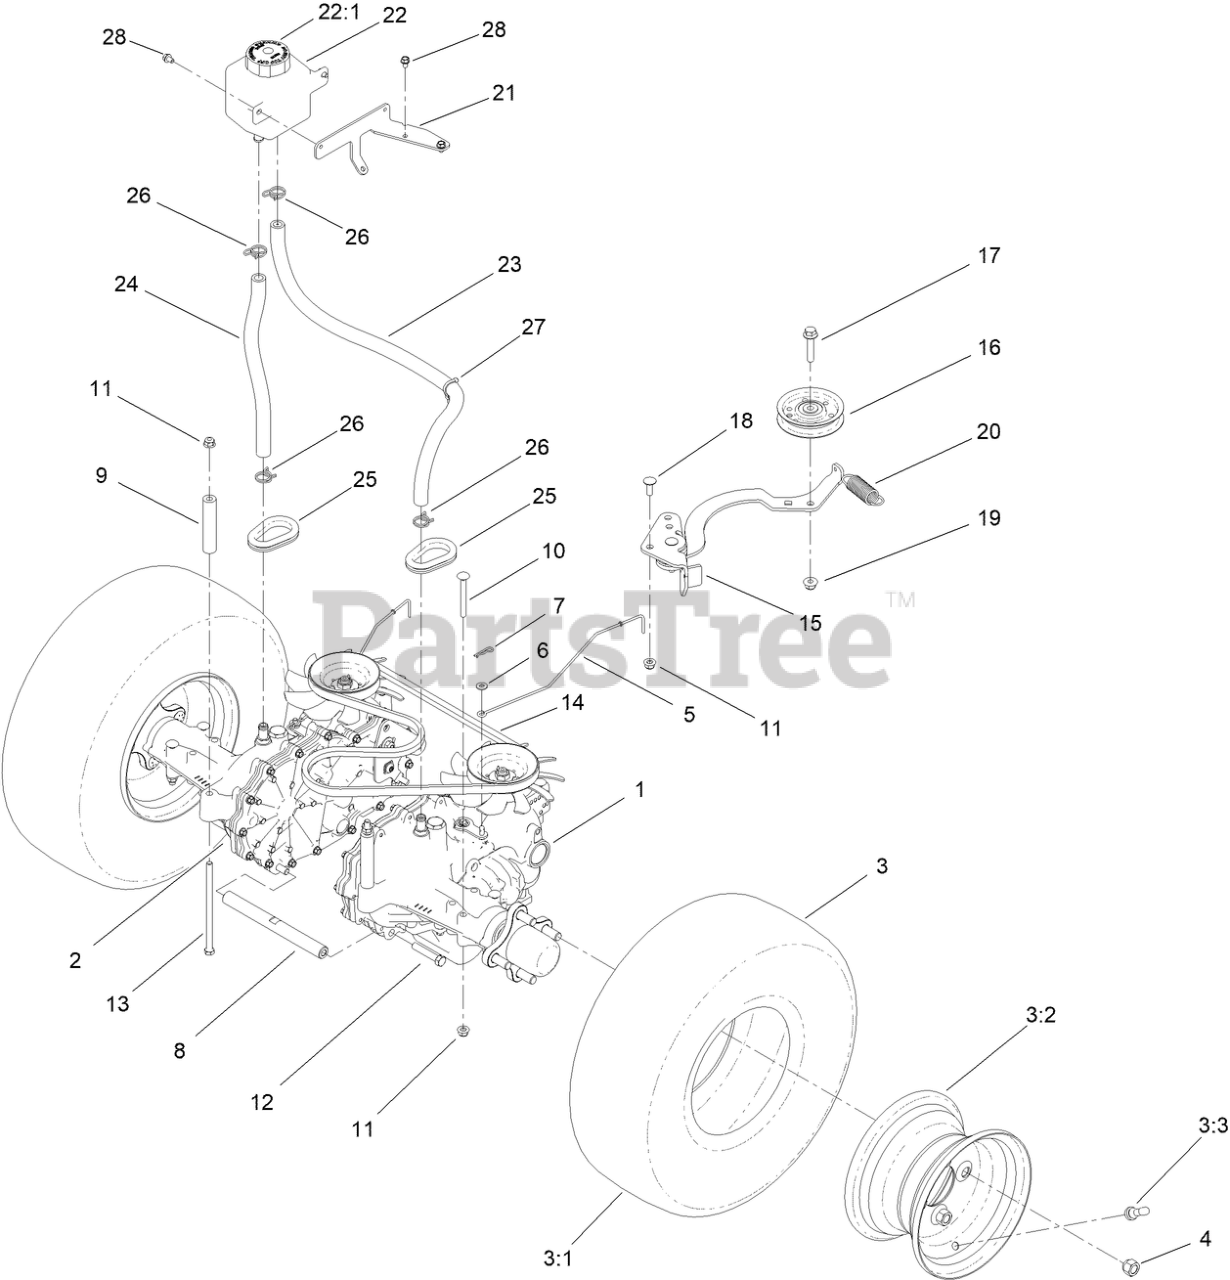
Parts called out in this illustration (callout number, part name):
1	TRANSMISSION, ZT-3100 LH
2	TRANSMISSION, ZT-3100 RH
3	WHEEL AND TIRE ASM
3:1	TIRE-4 PLY
3:2	RIM-8"
4	NUT-LUG
5	ROD-BYPASS
6	WASHER-FLAT
7	PIN-COTTER
8	SHAFT-CROSS, HYDRO
9	SPACER - TRANSMISSION
10	SCREW-CARR
11	NUT-HF, NI
12	SCREW-HH W/LOCTITE
13	SCREW-HH
14	BELT-V
15	IDLER ARM PIVOT ASM
16	PULLEY-IDLER, FLAT
17	SCREW-HHF
18	BOLT-CARR
19	NUT-HF, NI
20	SPRING-EXTENSION
21	BRACKET - EXPANSION TANK
22	TANK-HYD
22:1	CAP-RESERVOIR, HYD
23	HOSE-HYDRO
24	HOSE-OVERFLOW
25	GROMMET
26	CLAMP-HOSE
27	CLIP-TIE
28	SCREW-HWH
